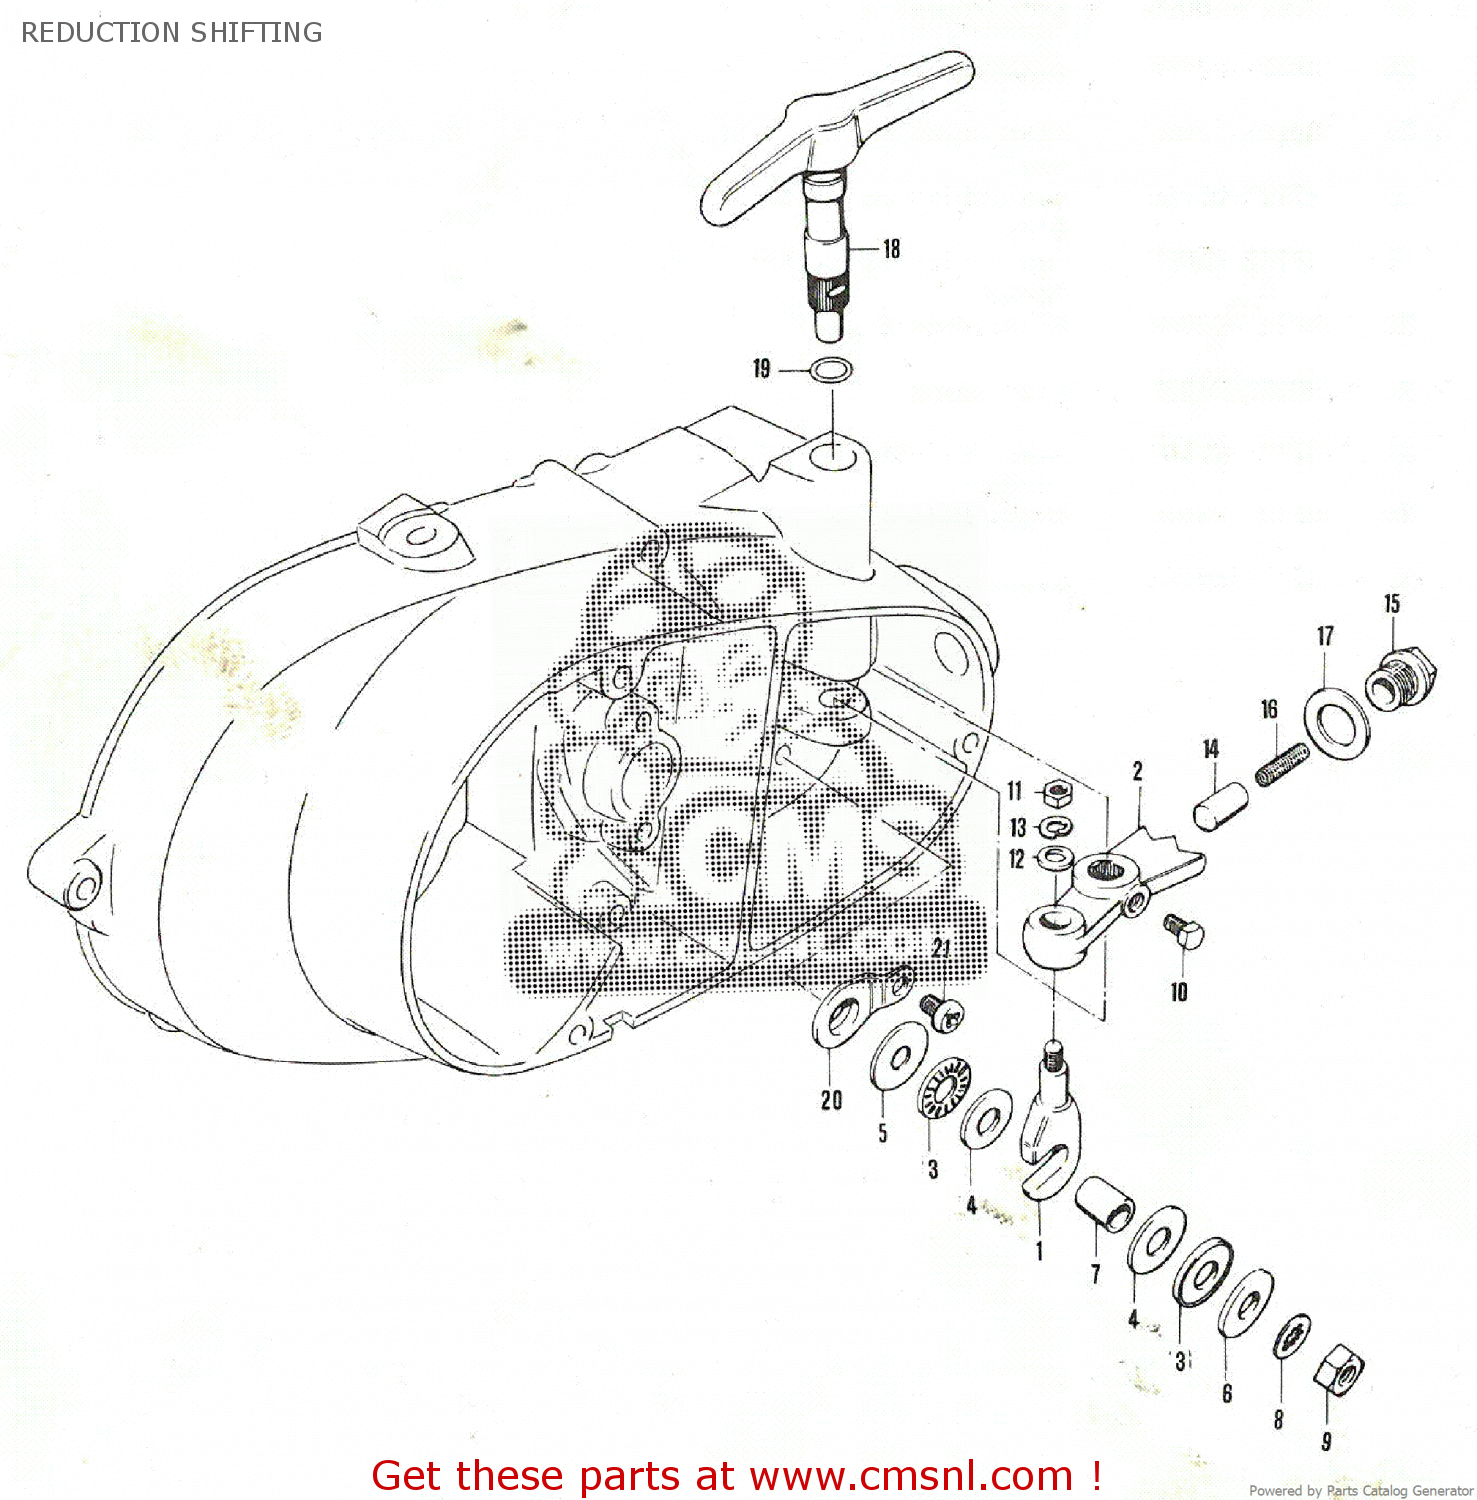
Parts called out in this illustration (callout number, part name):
1	REDUCTION SHIFTING ARM PIN
2	ARM,REDUCTION SHAFT
3	BEARING(10X22X2.8)
4	WASHER(10.1X21.4X0.8)
5	WASHER
6	WASHER (6X22X2)
7	SPACER(6X10X12.2)
8	LOCK WASHER
9	NUT
10	BOLT 5X16
11	NUT
12	WASHER
13	LOCK WASHER
14	STOPPER,GEAR SHIFTING
15	HOLDER,SHIFTING CAM STOPPER
16	SPRING
17	WASHER (16.5X42X2.6)
18	REDUCTION SHIFTING LEVER
19	O RING(D:1.3,ID:9.6)
20	REDUCTION ROD DUST SEAL
21	SCREW
